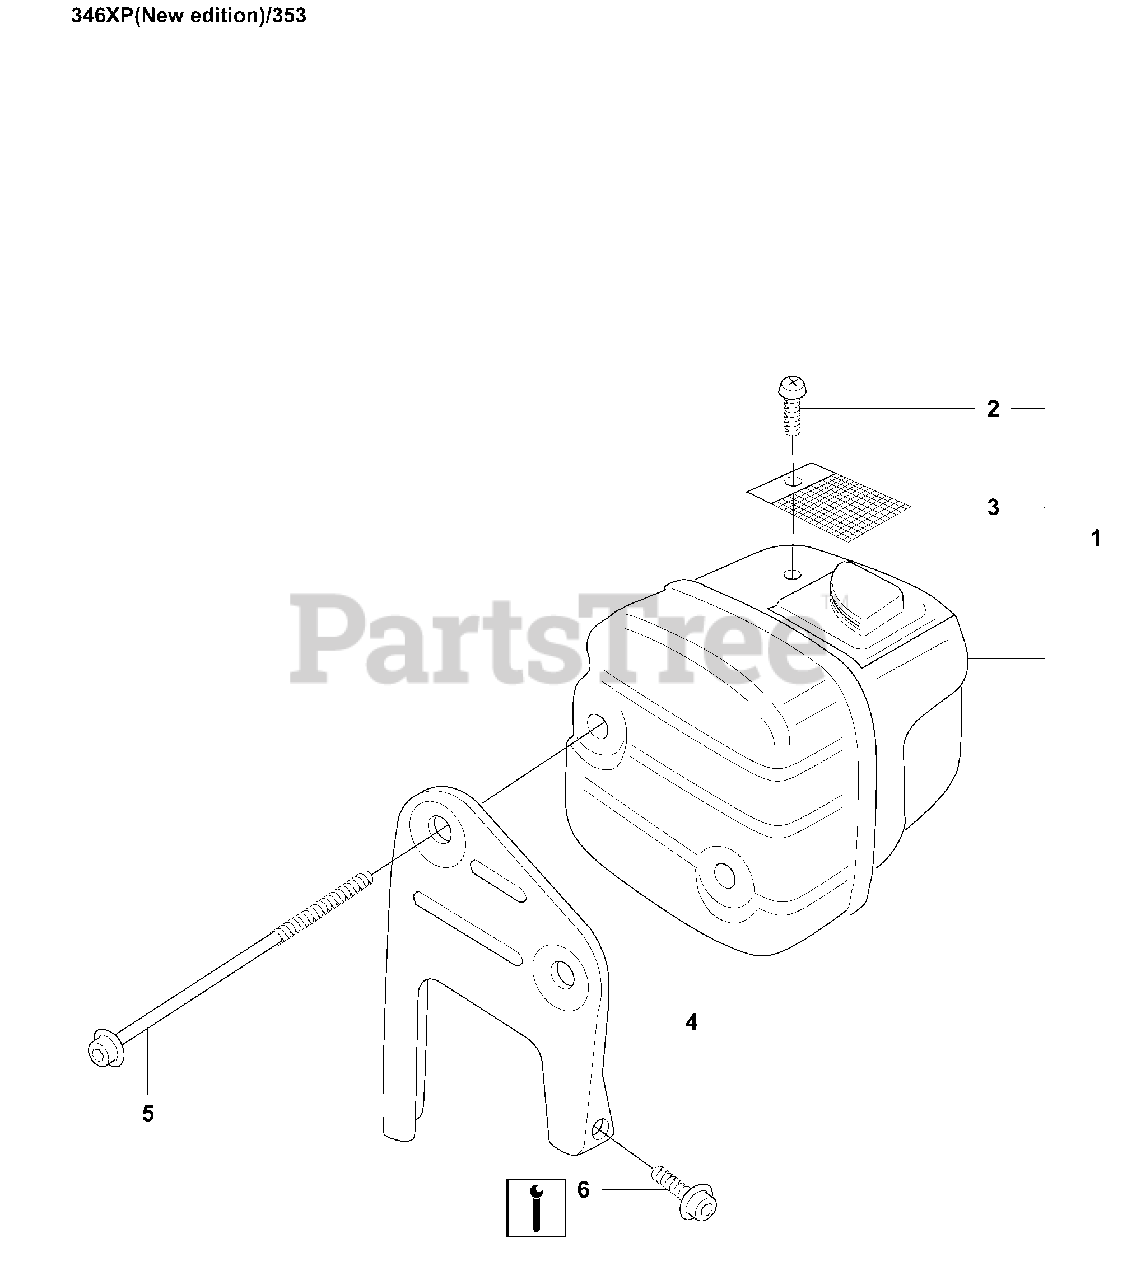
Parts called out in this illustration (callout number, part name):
1	MUFFLER ASSY
1	MUFFLER
3	RP SCREEN
